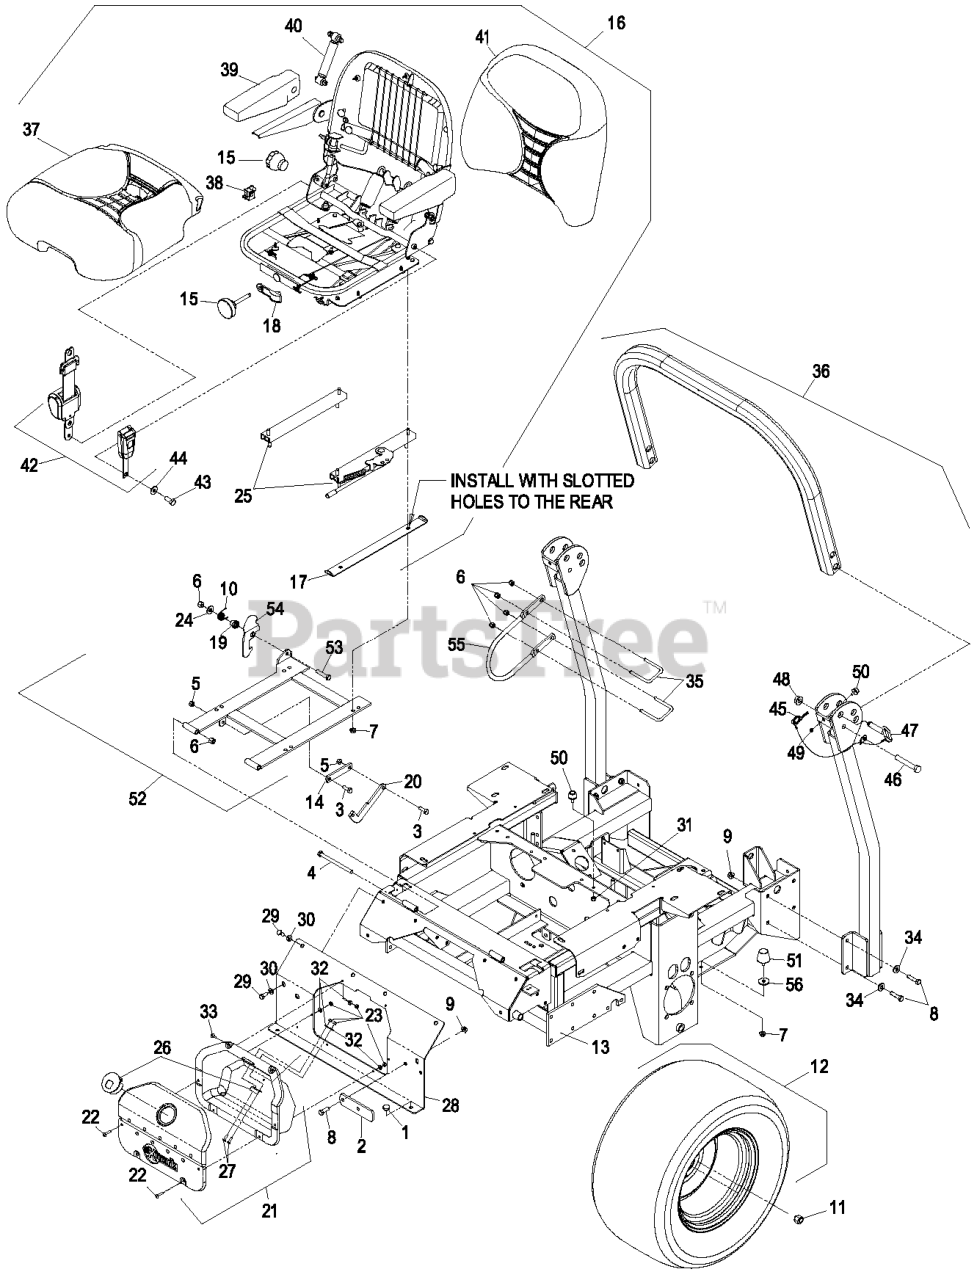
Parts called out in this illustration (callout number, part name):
2	STOP-BRAKE, PARK
3	SCREW-HH
4	SCREW-HH
5	NUT-LOCK, NI
6	NUT-LOCK, NI
8	SCREW-HH
9	NUT-HHF, WHIZ
10	SPRING-TORSION, LATCH
11	NUT-LUG
12	WHEEL AND TIRE ASM
13	ASM,KDXS ENGINE DECK W/DE
14	LINK-STOP, SEAT
15	KNOB KIT
16	Seat, Suspension
17	STOP/SPACER-SEAT
18	WEIGHT INDICATOR KIT
19	BUSHING-LATCH, SEAT
20	LINK-STOP, SEAT
21	ASM,CUBBY
23	NUT-LOCK, NI
24	WASHER-FLAT
25	SEAT TRACK KIT
26	LATCH,CUBBY
27	SCREW-PPH
28	ASM, CONSOLE W/DECALS
29	SCREW-HH
30	WASHER-PLAIN
31	NUT-LOCK, NI
32	WASHER-FLAT
33	SCREW-HEAD, TRUSS
34	WASHER-BELLEVILLE
36	KIT, 06 XS ROPS
37	BOTTOM CUSHION KIT
38	SWITCH-BAIL
39	PAD-ARMREST
40	SHOCK ABSORBER KIT
41	BACK CUSHION KIT
42	RETRACTABLE SEATBELT KIT
43	SCREW-HH
44	WASHER-SPRING
45	HAIRPIN
46	SCREW-HH
47	PIN-FOLD, ROPS
49	NUT-LOCK, NI
50	BUMPER-RUBBER
51	BUMPER-RUBBER
52	KIT,SEAT FRAME SERVICE
53	SCREW-HH
54	CATCH-LATCH, SINGLE
